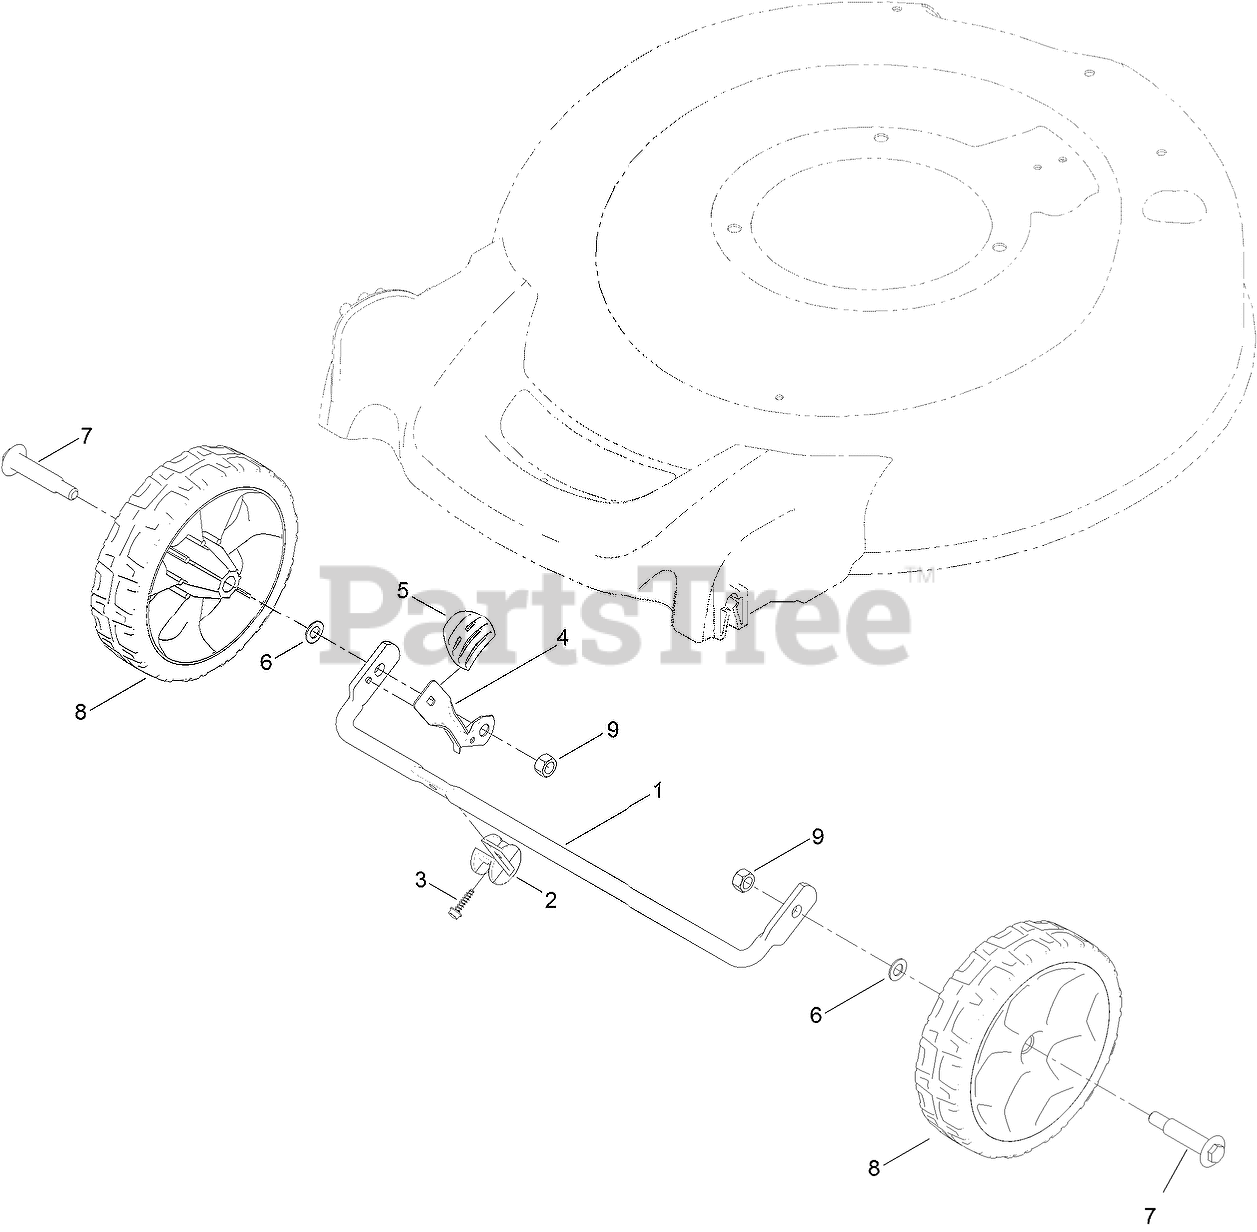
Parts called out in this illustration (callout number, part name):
1	AXLE-FRONT
2	STOP-AXLE
3	SCREW-HWH
4	ARM-SPRING
5	Knob-Lever, HOC
6	WASHER
7	BOLT-SHOULDER
8	7 INCH WHEEL ASM
9	NUT-HEX
